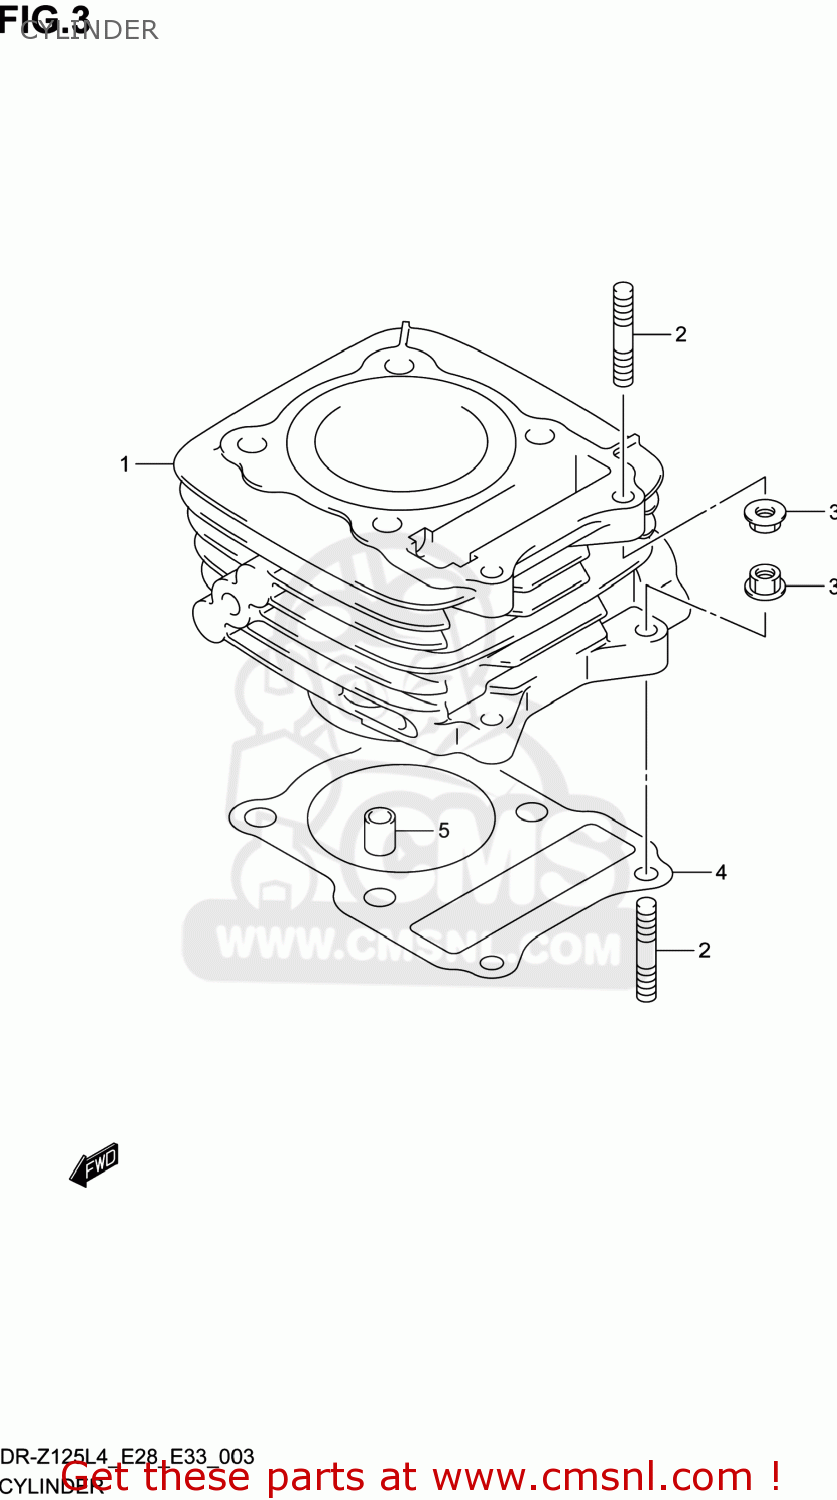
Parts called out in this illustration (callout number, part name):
1	CYLINDER
2	BOLT,STUD
3	NUT
4	GASKET,CYLINDER (NAS)
5	PIN
